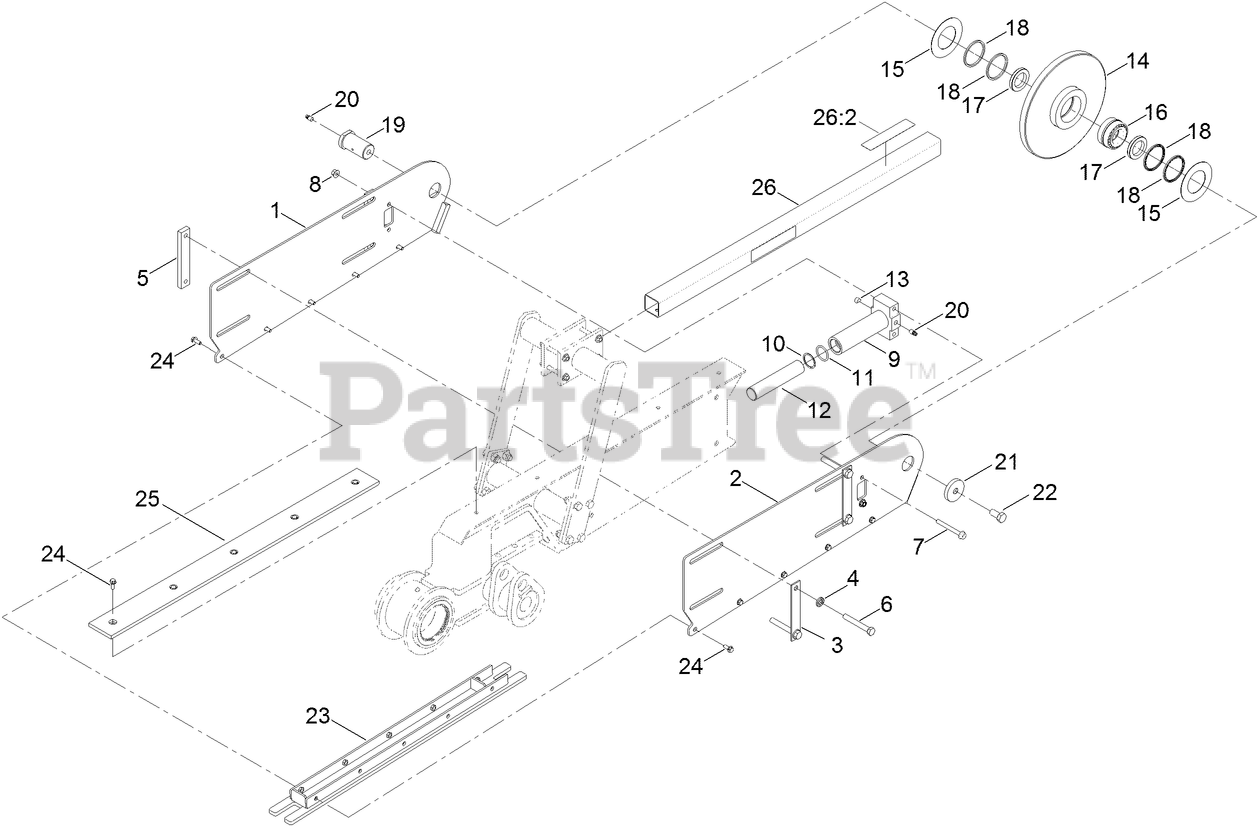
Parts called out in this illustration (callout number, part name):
1	PLATE-BOOM END, RH
2	PLATE-BOOM END, LH
3	BAR-CLAMP
4	WASHER-LOCK
5	BAR-TAPPED
7	BOLT-HHF
8	NUT-LOCK, HHF
9	BOOM END CYLINDER ASM
10	WASHER-BACKUP
12	ROD-BOOM, END (CYLINDER)
13	PLUG-BLEED
14	ROLLER-BOOM END
15	WASHER-BOOM, END (ROLLER)
16	BEARING KIT
17	SPACER-bearing
18	SEAL-ROLLER
19	PIN-BOOM
20	FITTING-LUBE, STRAIGHT
23	CHANNEL-WEAR, PAD
24	SCREW-HHF
25	BAR-WEAR, PAD
26	RESTRAINT-BAR, 48 INCH
26:2	DECAL-DANGER, ENTANGLEMENT
